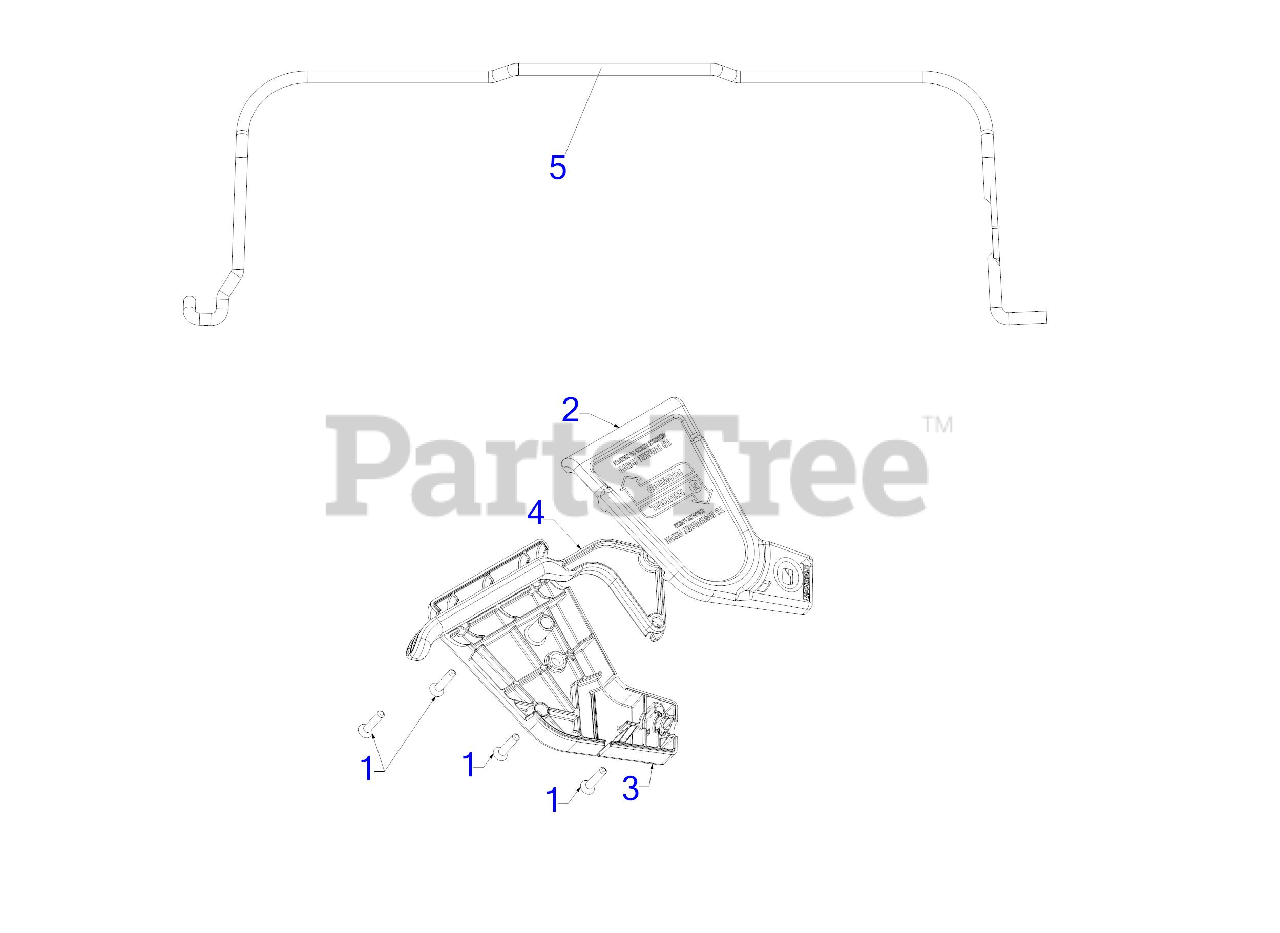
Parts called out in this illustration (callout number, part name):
1	SCREW #10-16 x 1.00
3	SQUEEZEBOX CONTROL COVER
4	SELF PROPELLED LEVER
